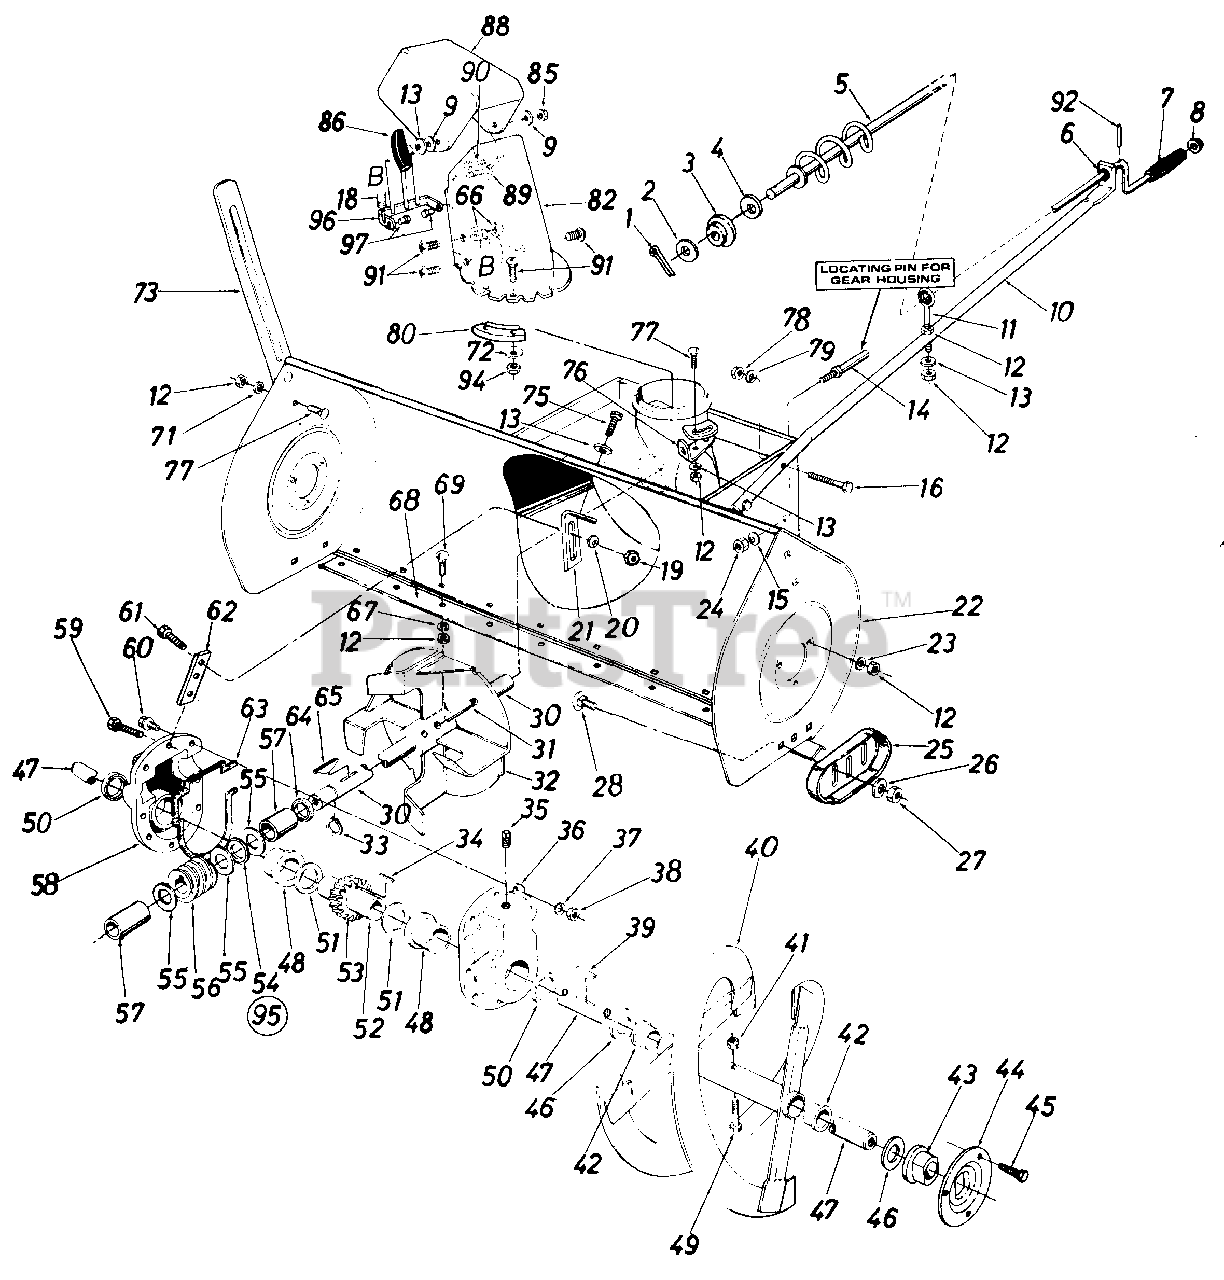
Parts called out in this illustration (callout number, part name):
2	Fl.-Wash. .39" I.D. x .62" O.D.
3	Plastic Bushing
4	Fl.-Wash. .385" I.D. x .62" O.D.
5	Chute Crank Ass'y.
6	Plastic Bushing
7	Knob (Black)
8	Push Nut 3/8" Rod
9	Fl.-Wash. .344" I.D. x 1.25" O.D.
10	Chute Crank Support Tubing
12	Hex Nut 5/16-18 Thd.*
13	Bell.-Wash. .345" I.D. x .88" O.D.
14	Stud 3/8-16 x 2.75" 4.
15	Bell.-Wash. .400" I.D. x.88" O.D.
16	Hex Bolt 3/8-24 x 1.25" 4.
18	Extension Spring
19	Hex Nut 1/4-28 Thd.
20	Bell.-Wash. .265" I.D. x .75" O.D.
22	45" Snow Blower Housing Ass'y.
23	L.-Wash. 5/16" I.D.
24	Hex Jam Nut 3/8-16 Thd.
25	Slide Shoe
26	Bell.-Wash. .400" I.D. x .88" O.D.
27	Hex Jam Nut 3/8-16 Thd.
28	Carriage Bolt 3/8-16 x .62" Lg.
30	Blower Axle .875" Dia. x 14.75" 4
31	Spring Pin Spir. 5/16" Dia. x 1.75" 4
34	#91 Woodr-Key 1/4 x 3/4" Dia. (HDN)
36	Gear Hsg. Half L.H.
37	Spr.-Wash. .32" I.D. x .62" O.D.
38	Hex Ins. L.-Nut 5/16-18 Thd.
39	#91 Woodr-Key 1/4 x 3/4" Dia. (HDN)
41	Hex Ins. L.-Nut 5/16-18 Thd.
42	Plastic Bushing
43	Flange Brg. w/flats 1" I.D.
44	Bearing Housing
45	Hex Sems Bolt 5/16-18 x .75" Lg.
46	Fl.-Wash. 1.00" I.D. x 1.75" O.D
48	Flange Bearing 1.503" I.D.
49	Shear Bolt 5/16-18 x 1.75" Lg.
50	Oil Seal 1.50" I.D.
51	Fl.-Wash. 1.50" I.D. x 2.00" O.D
52	Worm Gear Shaft
53	Double Threaded Worm Gear-L.H.
54	Thrust Brg.-.88" I.D. x 1.44" O.D.
55	Fl.-Wash. .88" 1 .D. x 1.4" O.D.
56	Double Threaded Worm-L.H.
57	Sleeve
58	Gear Hsg. Half-R.H.
59	Hex Bolt 5/16-18 x 1.25" 4.*
60	Hex Bolt 5/16-18 x 1.0" Lg. (Grade 5)
61	Hex Bolt 1/4-28 x .75" Lg.
62	Gear Housing Support Plate
63	Rubber Gasket
64	Oil Seal-.875" I.D.
65	#9 Hi-Pro Key 3/16 x 3/4" Dia. (HT.)
66	Hex L-Nut 1/4-20 Thd.
67	L.-Wash. 5/16" I.D.*
69	Carriage Boit 5/16-18 x 100" Lg.
71	L-Wash. 5/16" I.D.*
72	Fl.-Wash. 1/4" I.D.
73	Guide Blade
75	Hex Wash. Hd. AB 0 Tap Scr. 5/16" x .75" Lg.
77	Carriage Bolt 5/16-18 x .75" Lg.
78	Hex Ins. L.-Nut 3/8-24 Thd.
79	L.-Wash. 3/8" I.D.*
80	Chute Flange Keeper
82	Lower Chute
85	Hex Cent. L.-Nut 5/16-18 Thd.
86	Knob Handle
88	Upper Chute
89	Carriage Bolt 5/16-18 x 1.00" Lg.*
90	Truss Mach. Scr. 5/16-18 x .75" Lg.
91	Truss Mach. Scr. 1/4-20 x .75"
92	Roll Pin .12" Dia. x .63"
94	Hex Cent. L-Nut 1/4-20 Thd.
95	Gear Box Ass'y.-Comp.
97	Shld. Nut 1/4-20 Thd.
